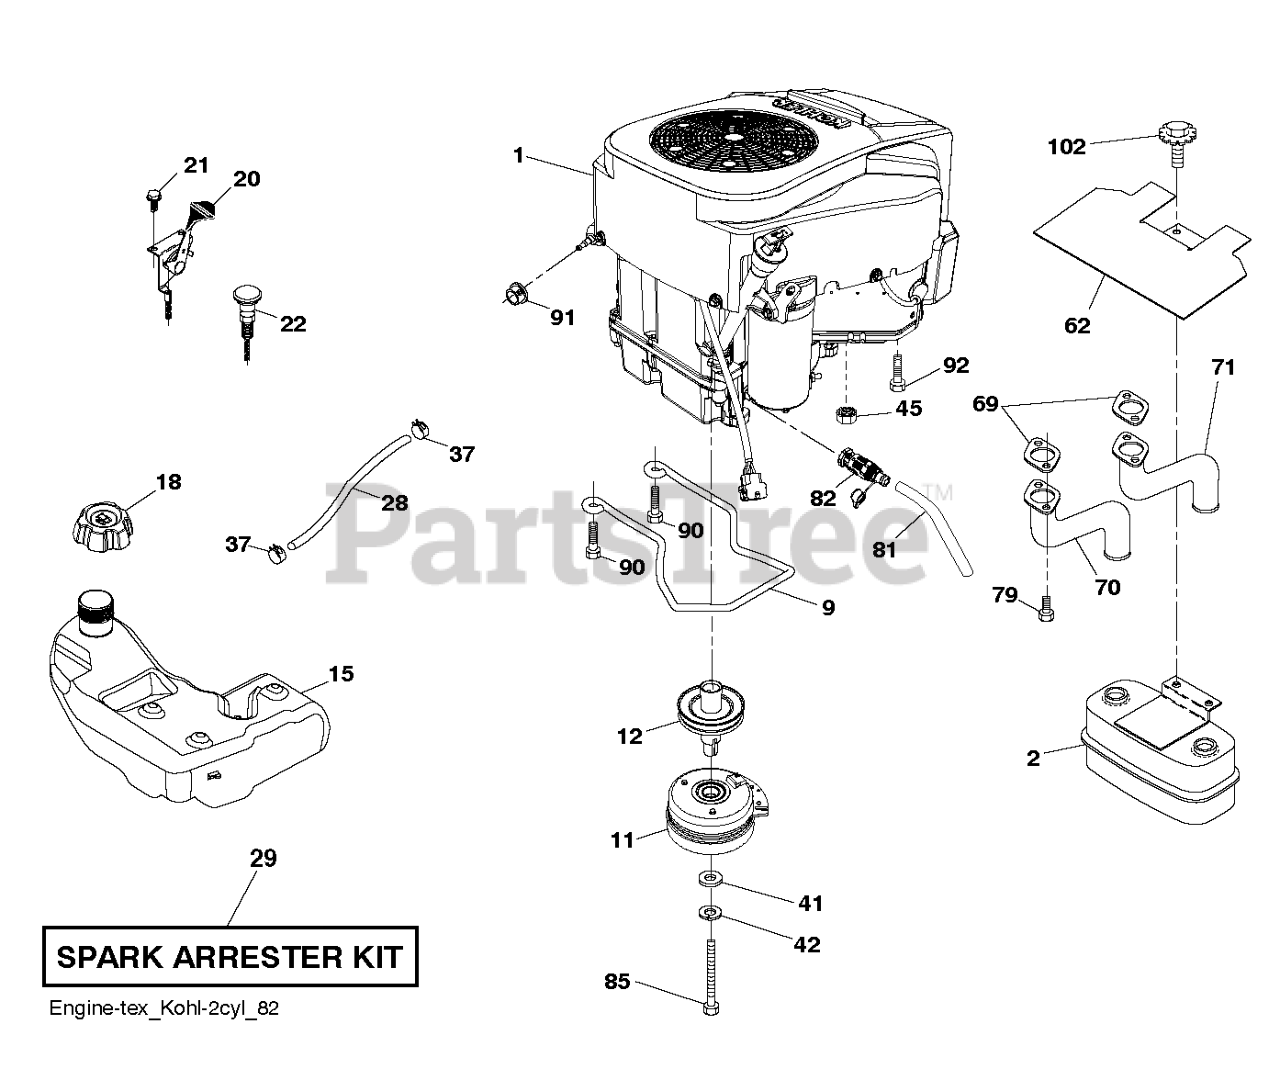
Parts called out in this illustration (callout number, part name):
2	MUFFLER.ASM.TWIN.MNTG.BRACKET
9	KEEPER.BELT.ENG.4.25"2.BLT.431
11	CLUTCH. 5.0 PD. 2.5 OFFSET
12	PULLEY.EXTENDED.SHAFT.GROUND
15	TANK.ASM.3GAL.EPA.18
18	CAP ASSY FUEL 3" GRAY
20	THROTTLE CONTROL
21	SCREW.#10 X 0.750.BOS
22	CONTROL.CHOKE.ERGO.PUSH-IN.BLA
28	HOSE.1/4".LOW.PERM.FUEL.LN.60"
29	KIT.SPARK ARRESTOR 794945 B&S
37	HOSE CLAMP
42	WASHER 7/16 LOCK
45	NUT
62	SHIELD.HEAT.MUFFLER
69	GASKET.EXHAUST.KOHL.CV18-CV26
70	PIPE.EXHAUST.LH.CV18/20
71	PIPE.EXHAUST.RH.CV18/20
79	SCREW.SOCKET HD.5/16-1
81	TUBE, DRAIN OIL ASM.
82	VALUE.OIL.DRAIN
85	BOLT.HEX.7/16-20X5.GR5.GREEN
90	SCREW 3/8-16X1
91	BUSHING.1.375OD
92	SCREW 3/8-16X1
102	SCREW
